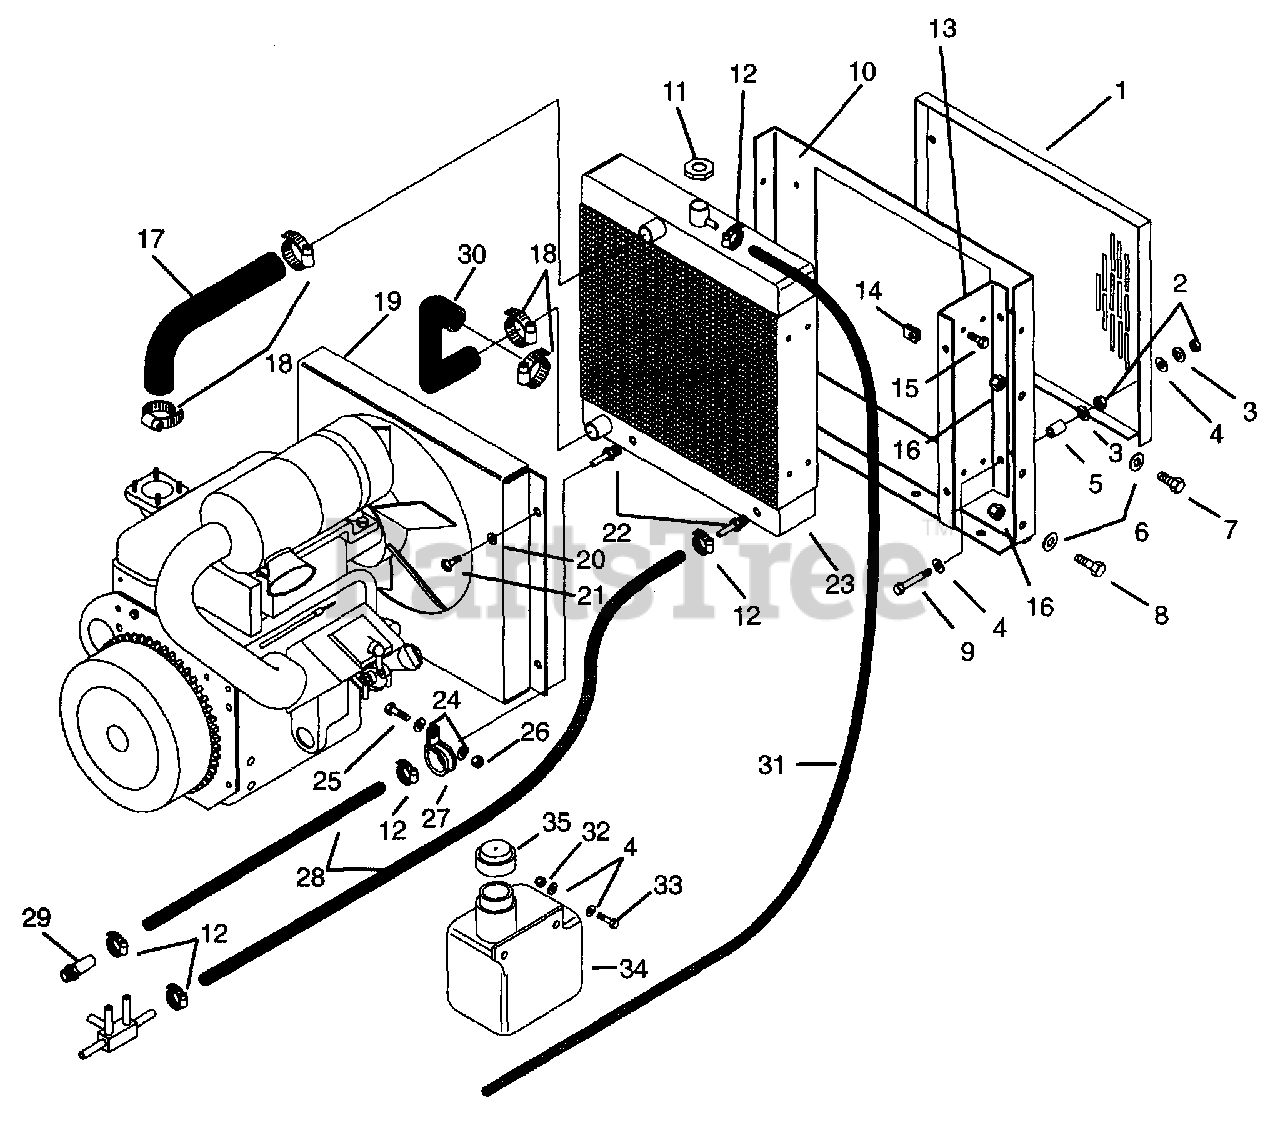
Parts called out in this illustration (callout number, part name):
1	Cover, Air
2	Nut-Hex .31-18
3	Washer-Lock .313 x .078
4	Washer-Flat-Steel .344 x .688 x .065
5	Bushing-Sleeve .407 x .625 x .750
6	Washer-Flat-Steel .531 x 1.06 x .095
7	Bolt-Hex .50-13 x 1 Grade 5
8	Bolt-Hex .50-13 x 1.50 Grade 5
9	Bolt-Hex .31-18 x 2.00 Grade 5
10	Mount, Radiator
11	Cap, Radiator
12	Hose Clamp
13	Bracket, Radiator
14	Nut-Retainer .25-20 x .56
15	Bolt-Hex .31-18 x .50 Grade 5
16	Nut-Locking-Center .50-13
17	Hose, Radiator Upper
18	Clamp-Hose 1.50 x .81 x 1.42
19	Weldment, Fan Cover
20	Washer-Flat-Steel .281 x .625 x .065
21	Screw-Machine .25-20 X .50
22	Adapter .38 Male Pipe to .38 Bead Tube
23	Radiator
24	Washer-Flat-Steel .406 x .812 x .065
25	Bolt-Hex .38-16 x 1.00 Grade 5
26	Nut-Locking .38-16
27	Clamp, Cushioned Steel
28	Hose, Hydraulic
29	Fitting-Adapter .562-18
30	Hose, Lower Radiator
31	Hose, 5/16 Inside Diameter
32	Nut-Locking-Nylon .31-18
33	Bolt-Hex .31-18 x 1.00 Grade 5
34	Connector, Hose
35	Tank, Plastic 1.5 Quart (Coolant)
36	Cap, 1-5/8 Vented
